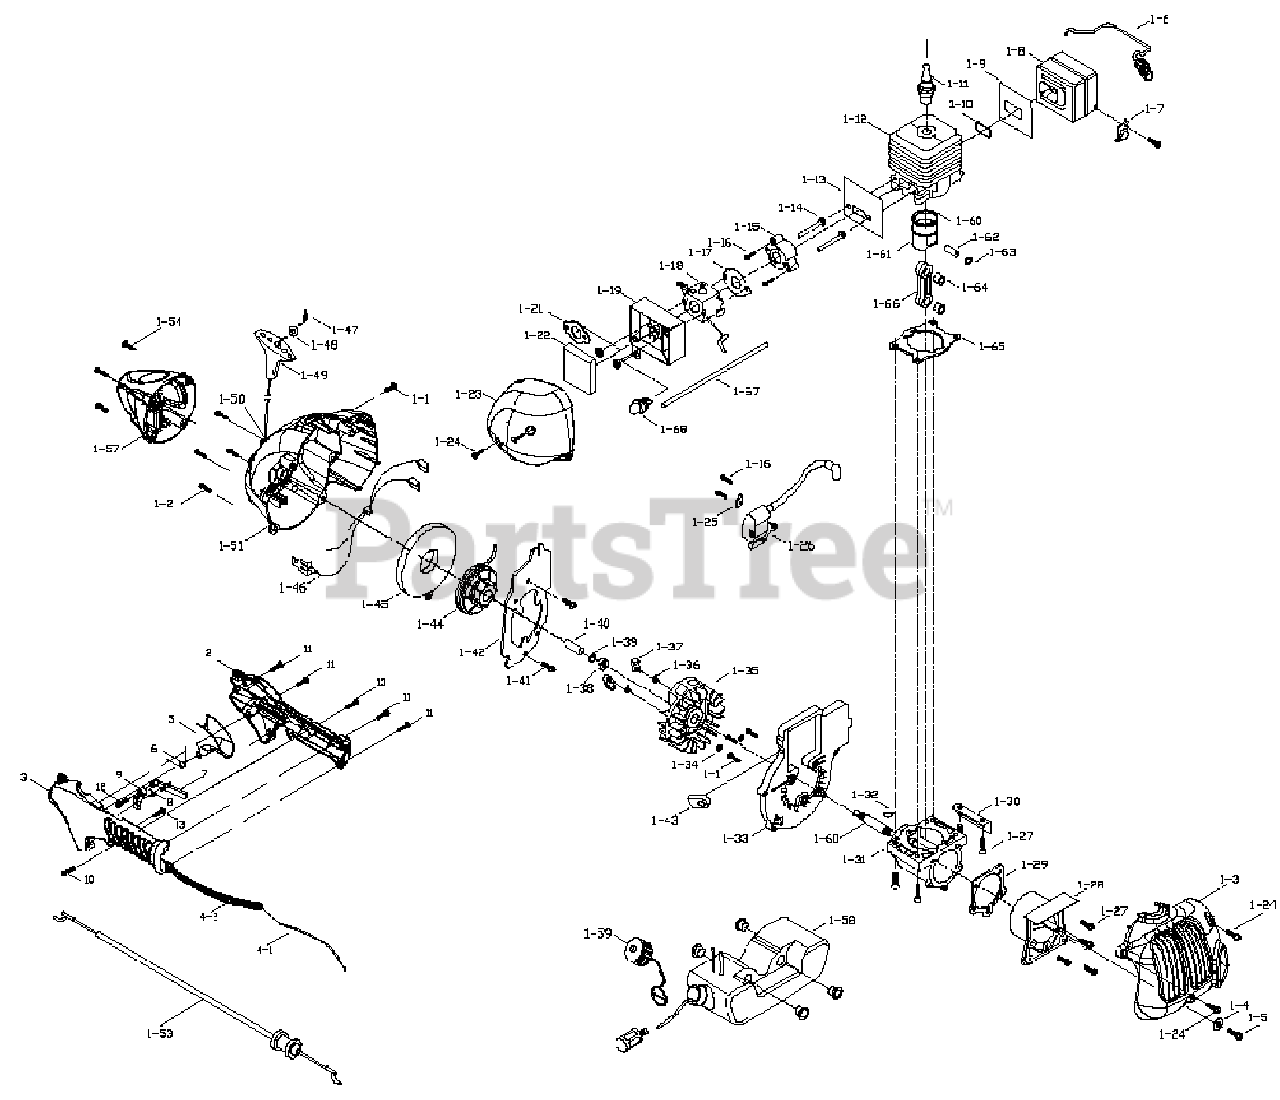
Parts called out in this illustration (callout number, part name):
1-2	WASHER, PLASTIC
1-6	SPRING, MUFFLER
1-8	KIT, MUFFLER
1-9	GASKET, MUFFLER
1-11	SPARK PLUG
1-13	GASKET, MANIFOLD
1-14	SCREW
1-15	MANIFOLD, CARBURETOR
1-17	GASKET, CARBURETOR
1-18	CARBUTETOR ASS'Y
1-21	TEMINAL TAB
1-22	FILTER, AIR
1-23	COVER, AIR CLEANER
1-26	IGNITION ASSEMBLY
1-30	SHIELD, MUFFLER
1-31	C'CASE ASS'Y
1-32	KEY, FLYHEEL
1-33	SHROUD, ENGINE
1-40	KIT, SPACER, CLUTCH
1-42	RETAINER, PULLEY
1-44	PULLEY, STARTER
1-45	PACKAGE, SPRING ASS'Y
1-46	WIRE ASS'Y,SWITCH
1-47	ROPE, STARTER
1-48	WASHER, NYLON
1-49	HANDLE, STARTER
1-50	GUIDE, ROPE
1-51	HOUSING (MTD YELLOW)
1-53	THROTTLE CABLE
1-54	SCREW
1-55	KIT, CLUTCH
1-56	DRUM ASS'Y, CLUTCH
1-57	HOUSING, CLUTCH
1-58	TANK ASS'Y
1-59	CAP ASS'Y, FUEL TANK
1-60	RING, PISTON
1-65	GASKET, CYLINDER
2	HOUSING HANDLE
3	HOUSING HANDLE
4-1	THROTTLE CABLE
7	LIBERATE SHAFT
9	LIBERATE CHUNK
